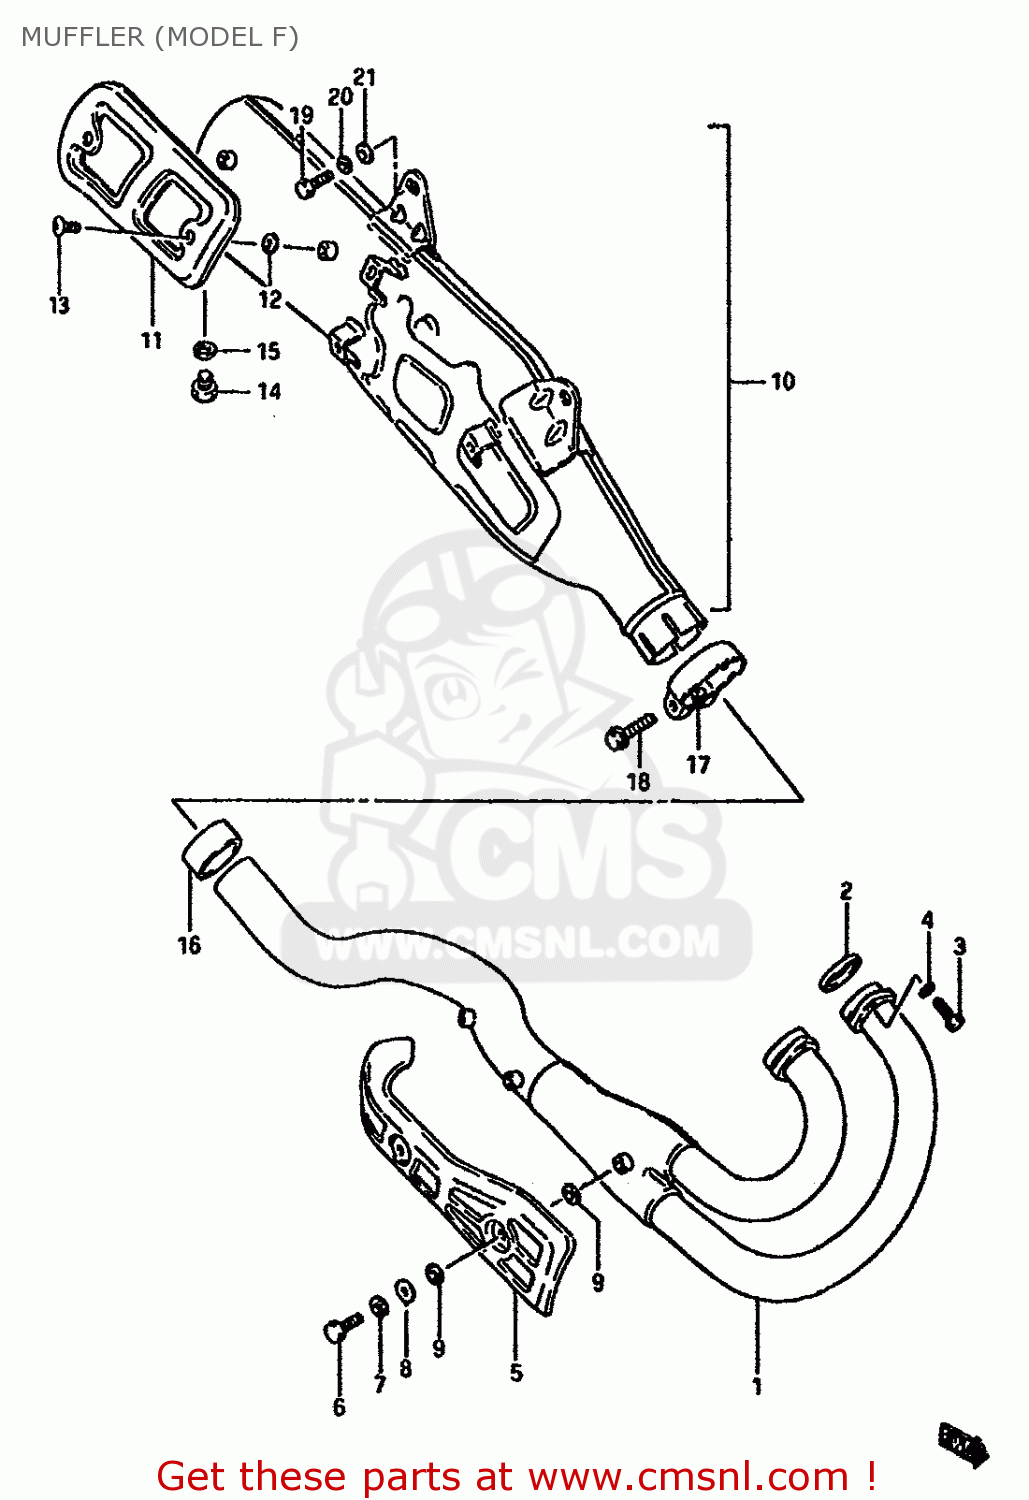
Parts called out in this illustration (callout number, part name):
1	PIPE,EXHAUST
2	GASKET,EXHAUST PIPE
3	BOLT
4	WASHER,LOCK
5	COVER,EXHAUST PIPE
6	BOLT
7	WASHER,LOCK
8	WASHER
9	GASKET
10	MUFFLER ASSY
11	COVER,MUFFLER
12	GASKET,EXHAUST PIPE
13	SCREW
14	PLUG,12X9
15	GASKET(12.1X16.2X3.7) (NAS)
16	CONNECTOR,MUFFLER
17	CLAMP,MUFFLER CONNECTOR
18	BOLT 8X40
19	BOLT
20	LOCK WASHER
21	WASHER
